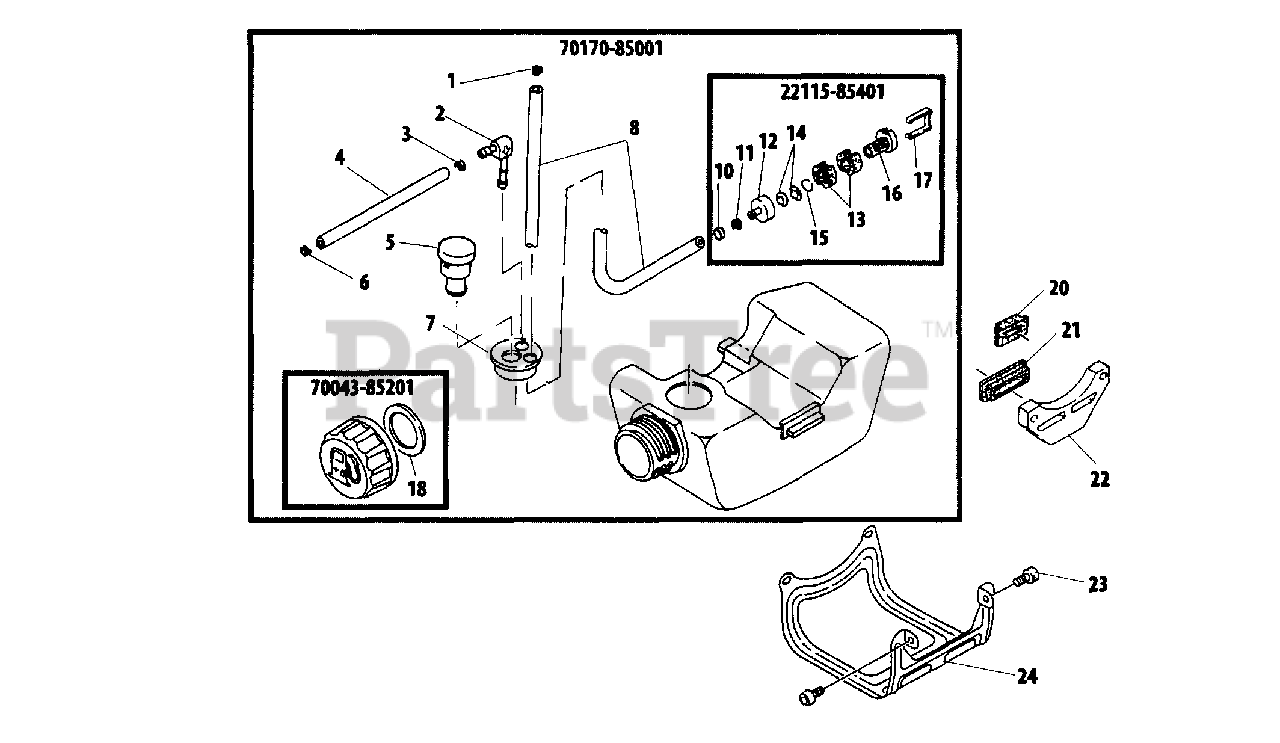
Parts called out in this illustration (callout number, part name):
1	CLIP
2	CONNECTOR, PIPE
3	CLIP
4	PIPE, RETURN
5	VENT ASSY
6	CLIP
7	GROMMET, FUEL TANK
8	PIPE, FUEL
10	VALVE, CHECK
11	CLIP
12	WEIGHT, FUEL LINE
13	FILTER, FUEL
14	STRAINER
15	RING, RETAINING
16	BODY, FUEL FILTER
17	CLIP, FILTER
18	GASKET, FUEL CAP
20	CUSHION, FUEL TANK
21	CUSHION, FUEL TANK - REAR
22	BRACKET, FUEL TANK
23	BOLT M5×12
24	GUARD, METAL FUEL TANK
